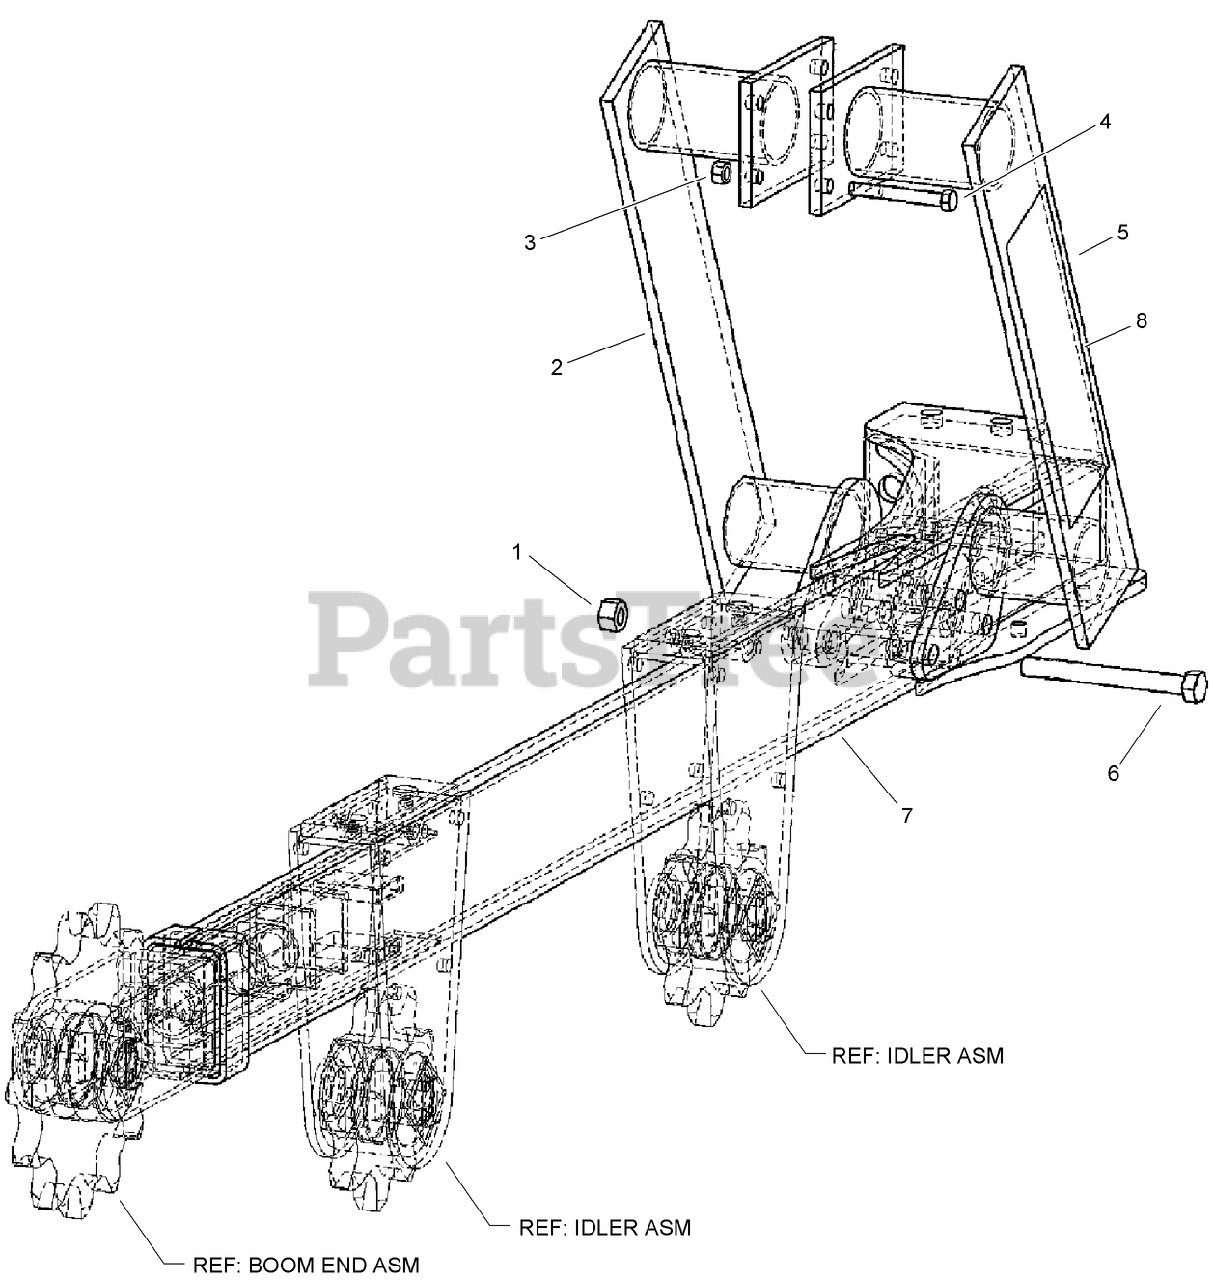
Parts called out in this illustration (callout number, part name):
1	NUT-Prev Trq 3/4 GRC CAD Direct
2	MOUNT-Crumber, LH
3	NUT-HEX
4	SCREW-HH
5	MOUNT-Crumber, RH
7	BOOM-trencher, 6 foot, heavy duty planetary drive trencher
8	DECAL-Danger, Sharp Parts (large)
